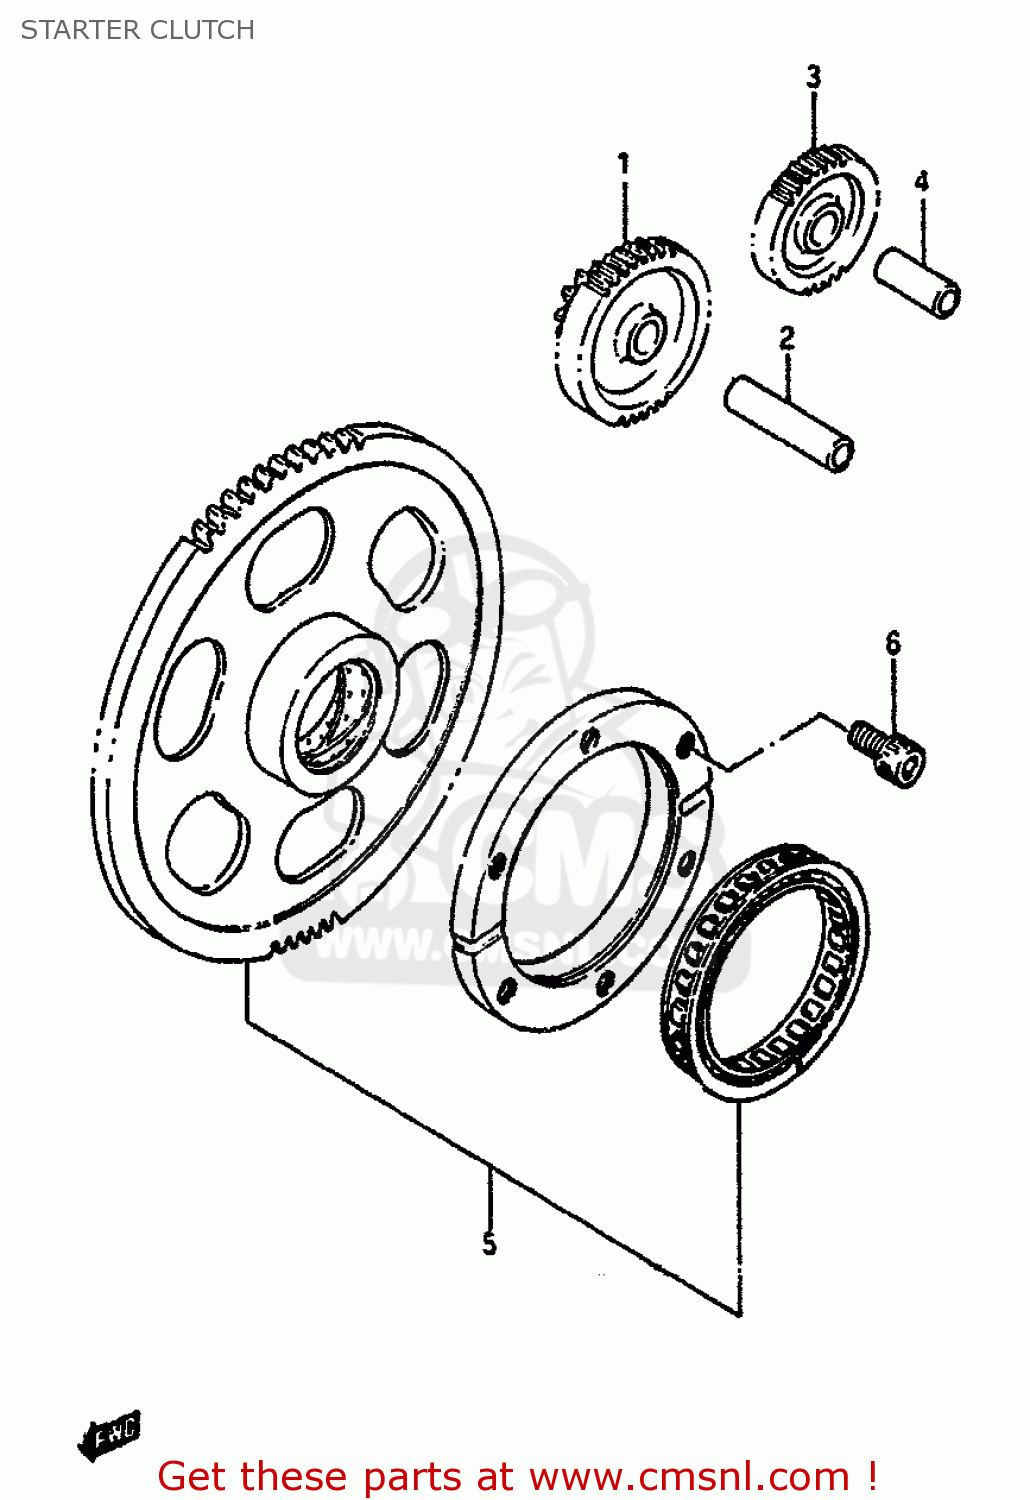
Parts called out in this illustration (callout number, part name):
1	GEAR,STARTER IDLE NO.1
2	PIN
3	GEAR,STARTER IDLE NO.2
4	PIN
5	CLUTCH SET,STARTER
6	BOLT
